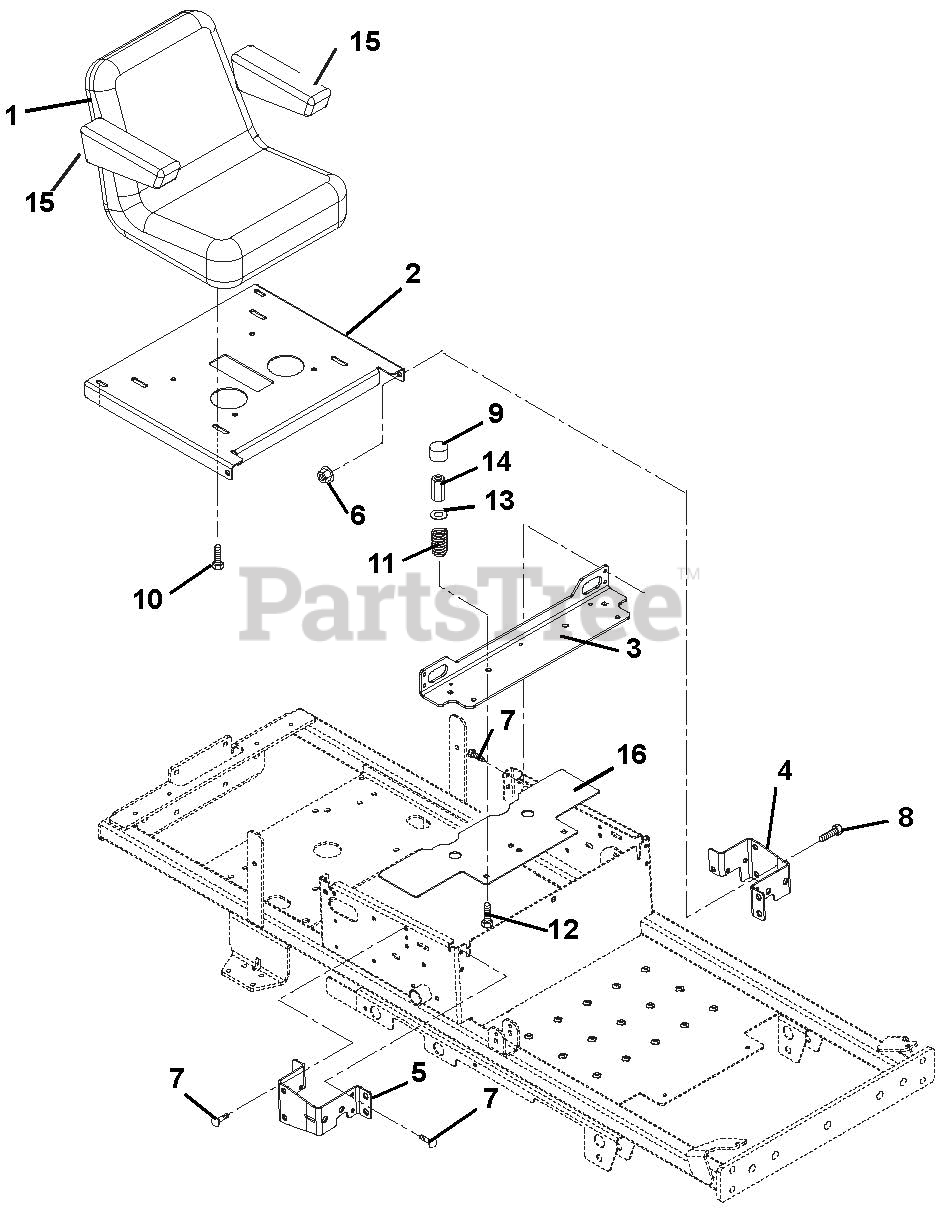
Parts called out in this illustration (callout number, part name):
1	SEAT,V-2505 MICHIGAN W/ARM
2	SEAT PLATE
3	BRKT, SEAT SPRING
4	WDMT, RH STEERING STOP
5	WDMT, LH STEERING STOP
6	@NUT-LK-TOP-FLG .38-16 YWZC
7	@SCR-TAP .31-18X.50 HWH TR YWZ
8	BOLT-SHLDR .375-16X.150
9	HUB CAP
10	5/16-18X3/4 HX/W/HD WHIZ
11	SPRING, SEAT
12	@BLT-RDHDSQNK .31-18X1.50 G5YZ
13	WSHR-FL-STL .328X.87X.179 YWZC
14	NUT, COUPLING 5/16-18 X 1 3/4
15	KIT,ARMREST PAD ONLY 1 PER KIT
16	GUARD, ZOOM FINGER
